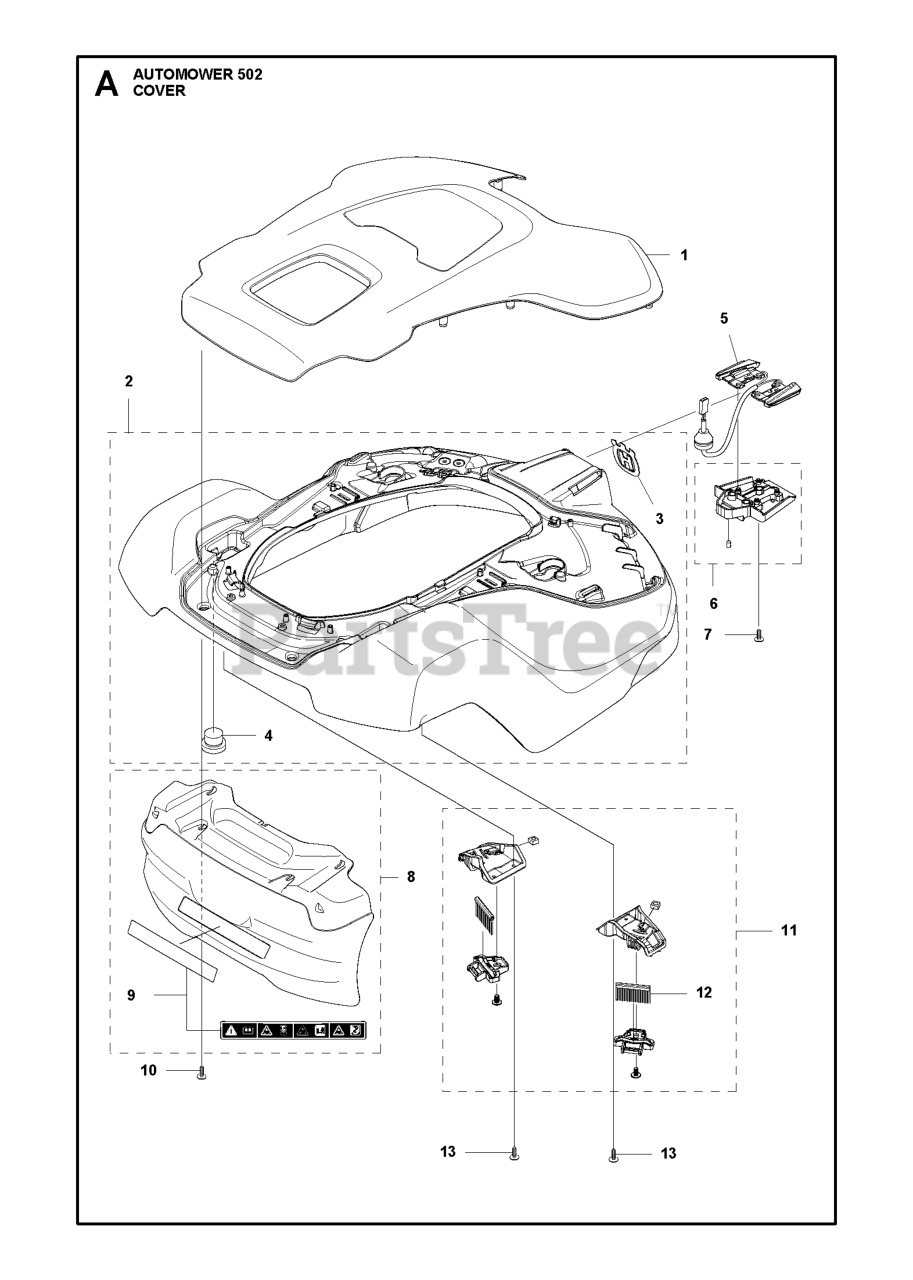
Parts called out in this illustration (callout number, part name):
2	BODY ASSY
3	DECAL HUSQVARNA CROWN HEIGHT 5
4	CAP SNAPLOC
5	CABLE ASSY CHARGING PLATE
6	HOLDER ASSY MAGNET
7	SCREW 14MM
8	BUMPER ASSY
9	LABEL WARNING P15
10	SCREW ITXPANT
11	BRUSH KIT 430/450
12	WHEEL BRUSH REFILL KIT
13	SCREW 14MM
